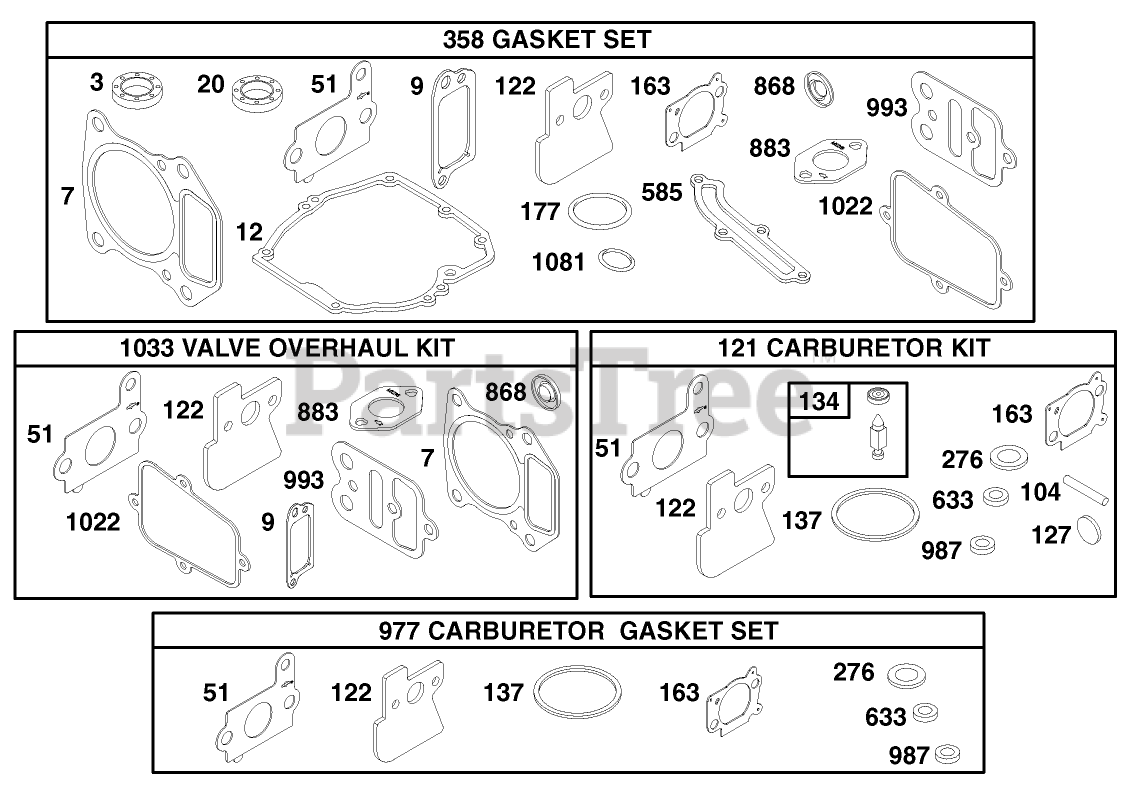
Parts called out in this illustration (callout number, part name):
3	Seal-Oil
7	Cylinder Head Gasket
9	Gasket?Breather
12	Gasket
20	Seal-Oil
51	Intake Gasket
104	Spring
121	Carburetor Overhaul Kit
122	Gasket-Intake
127	Welch Plug (Sold in Kit Only)
134	Valve-Inlet (Includes Seat)
137	Float Bowl Gasket (Sold in Kit Only)
163	Air Cleaner Gasket
177	O-Ring Seal
276	Washer (Sold in Kit Only)
358	Gasket Set
585	Gasket-Breather
708	Choke Shaft Seal (Sold in Kit Only)
868	Valve Seal
883	Exhaust Gasket
977	Gasket Set?Carburetor
987	Throttle Shaft Seal (Sold in Kit Only)
993	Gasket
1022	Rocker Cover Gasket
1033	Valve Overhaul Kit
1081	O-Ring Seal
